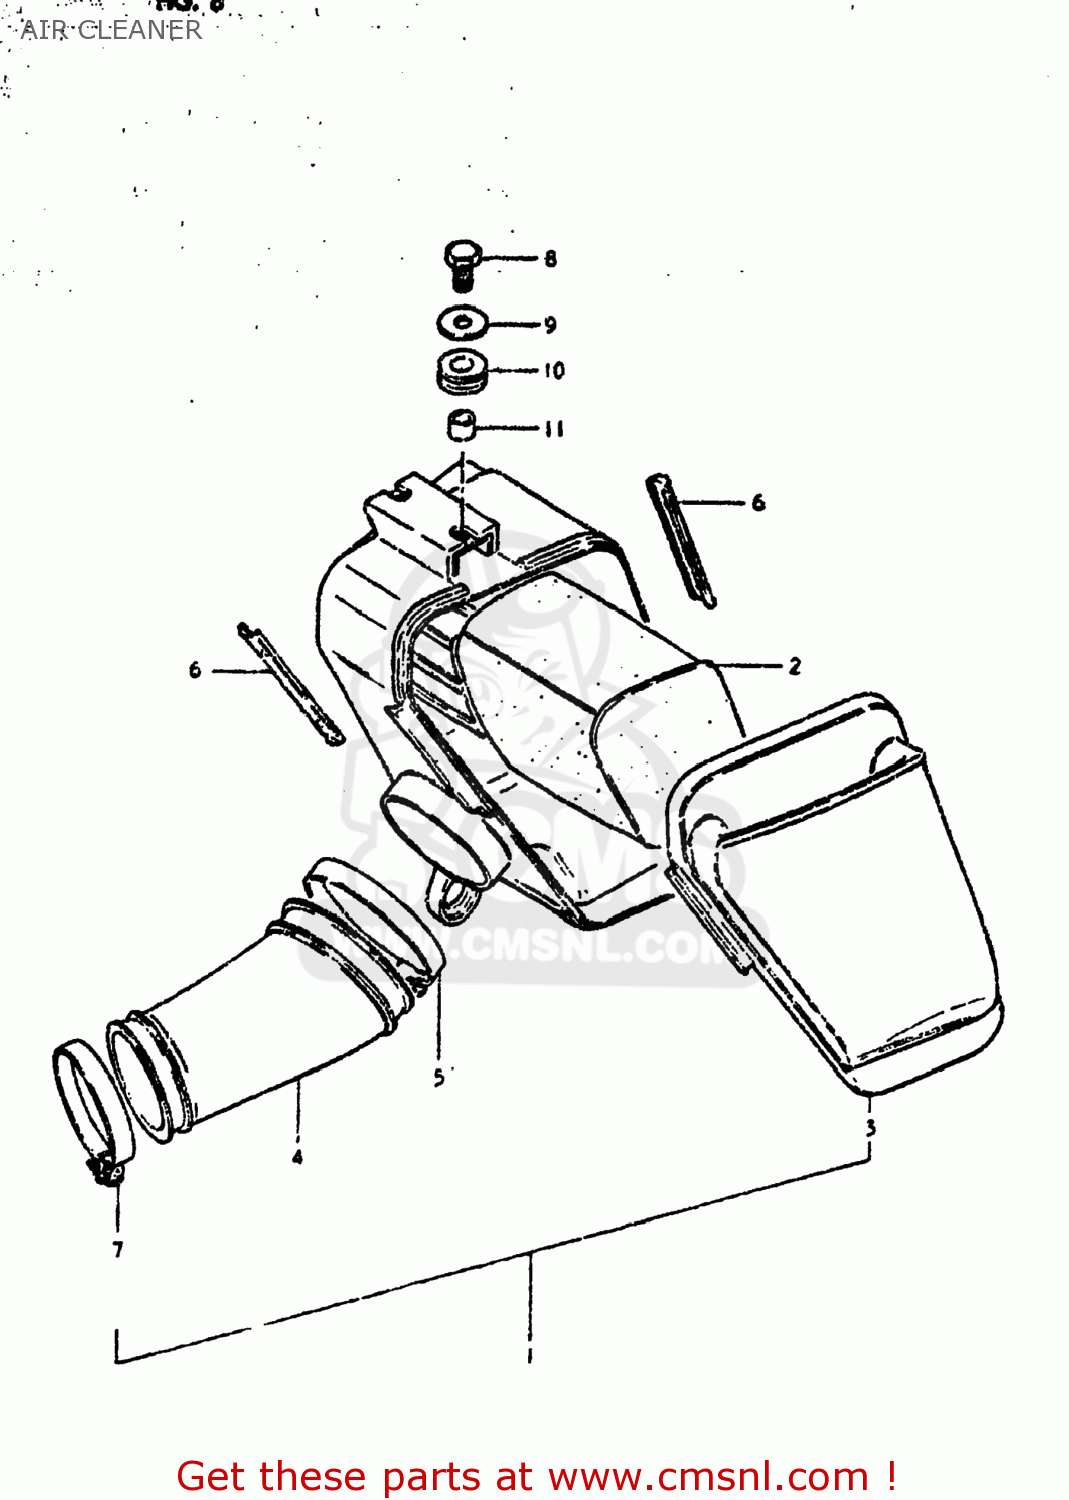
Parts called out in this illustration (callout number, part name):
1	CLEANER ASSEMBLY,AIR
2	FILTER
3	CAP,AIR CLEANER
4	OUTLET
5	CLAMP
6	SLIDER
7	CLAMP
8	BOLT, UPPER
9	WASHER
10	CUSHION
11	SPACER (7X9X7)
